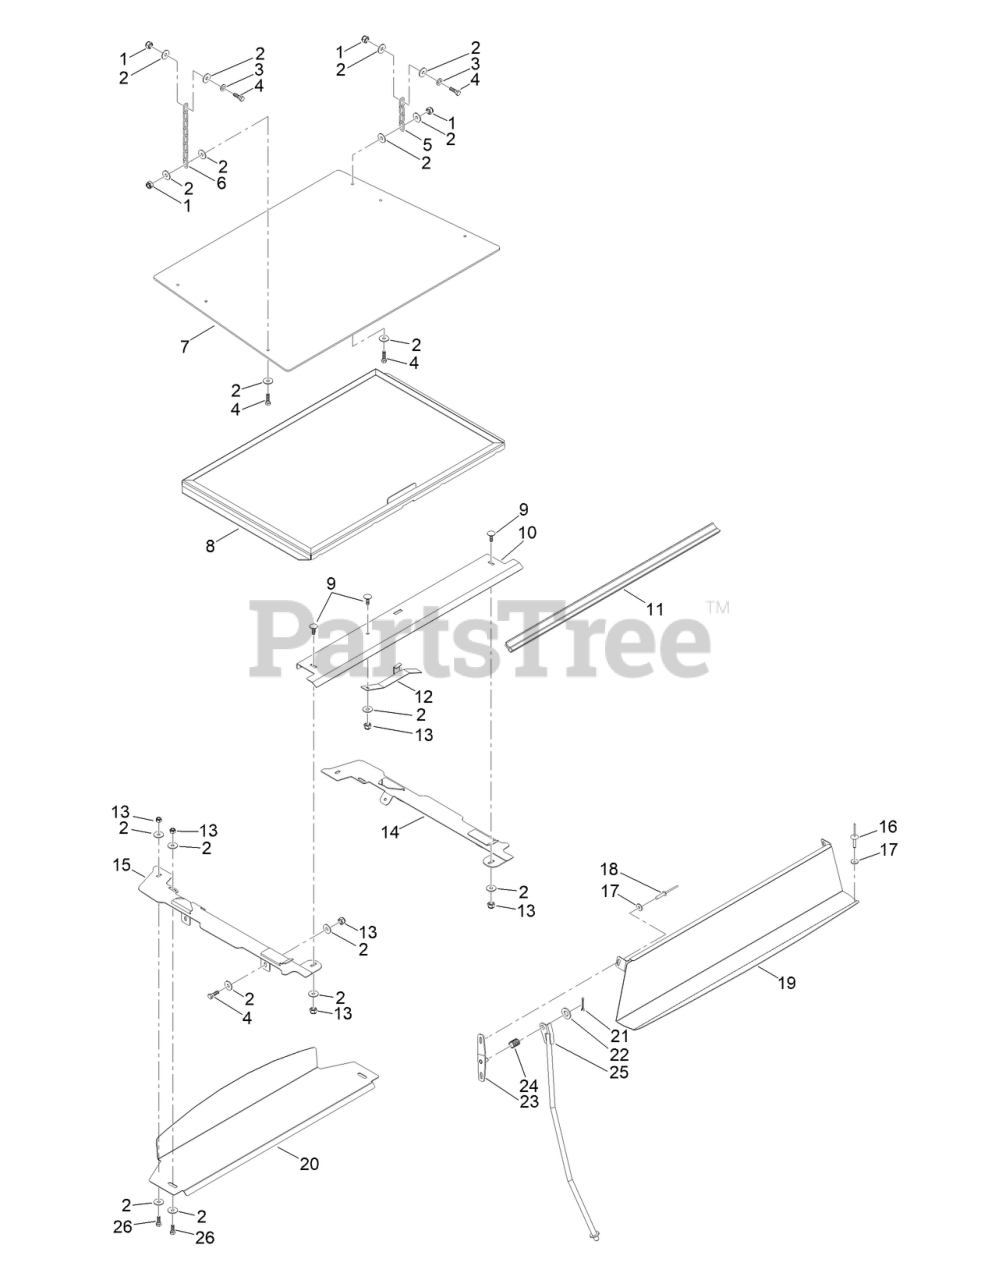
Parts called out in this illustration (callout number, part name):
2	WASHER
3	WASHER
7	PANEL-PLASTIC, GRASS CATCHER
8	GRID, REMOVABLE
10	SUPPORT, REMOVABLE GRID
11	GASKET
12	HANDLE, HOPPER GRID
14	SLIDE, REMOVABLE GRID ? RH
15	SLIDE, GRID LH
17	WASHER
19	GRID, DOOR
20	PLATE, HOPPER GRID
21	PIN-SPRING
22	WASHER
23	SUPPORT
24	SPRING
